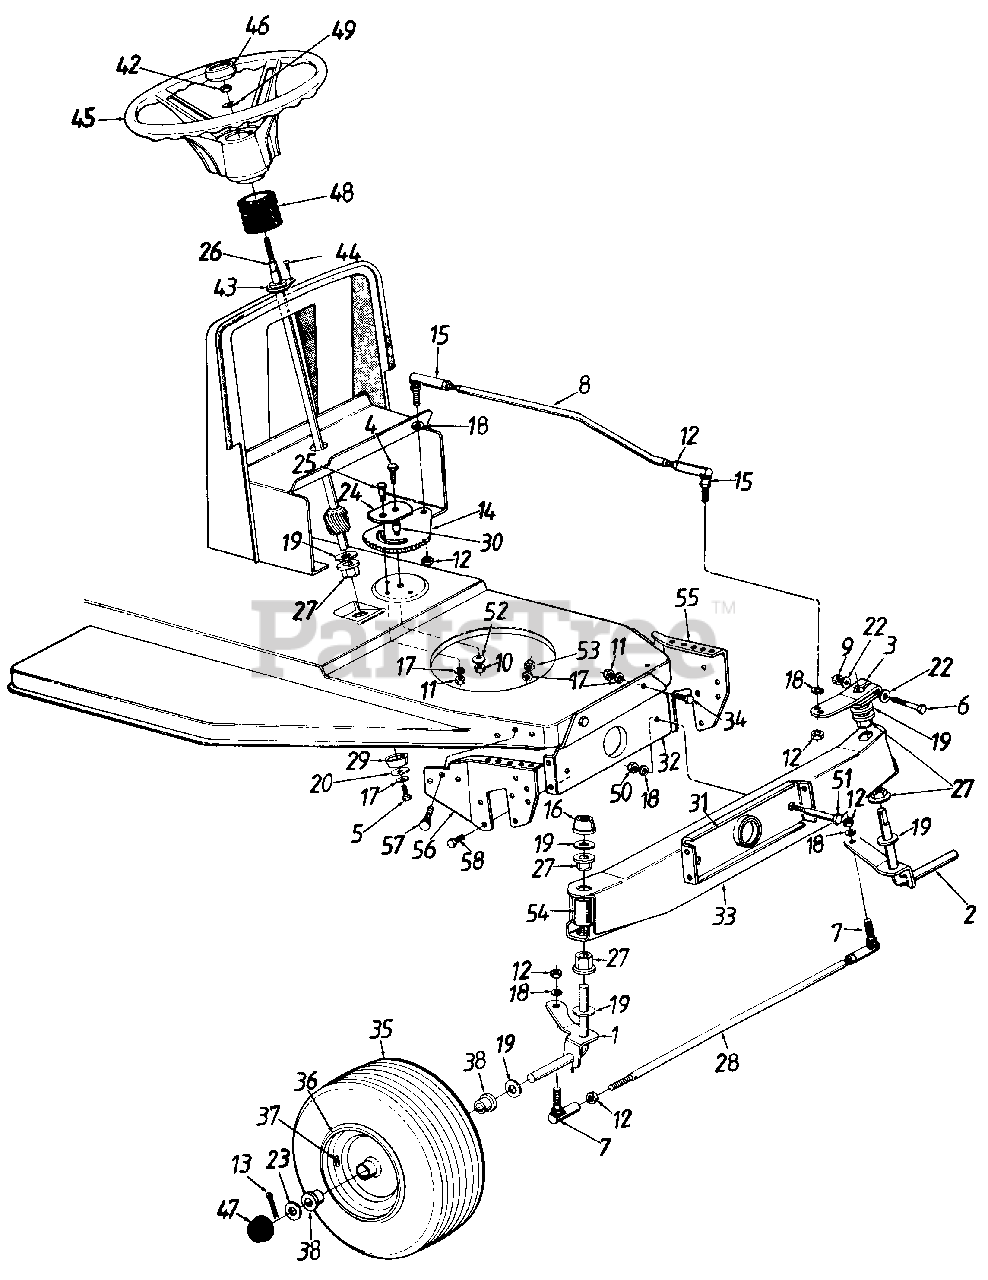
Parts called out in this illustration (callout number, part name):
1	Front Axle Ass'y.-R.H.
2	Front Axle Ass'y.-L.H.
3	Steering Arm
4	Hex Bolt 3/8-24 x 1" Lg.
5	Hex Bolt 5/16-18 x .62"
6	Hex Bolt 5/16-24 x 2" Lg.
7	Ball Joint 3/8-24 Thd.
8	Steering Drag Link
9	Hex L-Nut 5/16-24 Thd.
10	Hex Nut 3/8-24 Thd.
11	Hex Nut 5/16-18 Thd.
12	Hex Jam Nut, 3/8-24 Thd.
13	Cotter Pin 1/8 Dia.
14	Steering Gear Segment
15	Drag Link Ball Joint 3/8-24 Thd.
17	L-Wash. 5/16" I.D.
18	L-Wash. 3/8" I.D.
19	Fl-Wash. .64" l.D. x 1.24"
20	Fl-Wash. .340" I.D. x 1.125"
22	Spr. Wash. 82" l.D. x .62n
23	Fl-Wash. .635" I.D. x 1.585n
24	Retainer Plate
25	Shld. Bolt .437" Dia. x .350"
26	Steering Shaft
27	Hex Flange Brg. .634 Dia.
28	Tie Rod 20" Lg.
29	Spacer .985" I.D.
30	Spacer .380" l.D.
34	Hex Bolt 5/16-18 x .75" Lg.
35	Front Wheel Ass'y. Comp. 15" x 6"
36	Rim Ass'y. Only
37	Air Valve
38	Bronze Bearing .63" l.D.
42	Hex L-Nut 5/16-24 Thd.
43	Steering Column Brg.
44	Cr-Sunk Scr. #10 x 5/8{" Lg.
45	Steering Wheel
46	Steering Wheel Cap
47	Hub Cap
48	Bellow Steering Column
49	Bell-Wash. .345" l.D. x .88n
50	Hex Nut 3/8-16 Thd.
51	Shld. Bolt 1/2" Dia. x 2.04"
52	Bell-Wash. .39" x 1.38" O.D.
53	Hex Nut 5/16-24 Thd.
54	Plastic Tube
55	Pivot Bar Side Plate-L.H.
56	Pivot Bar Side Plate-R.H.
57	Rib Neck Bolt 5/16-24 x .84" Lg.
58	Hex Wash. Tap Scr. 5/16-18 x .62" Lg.
